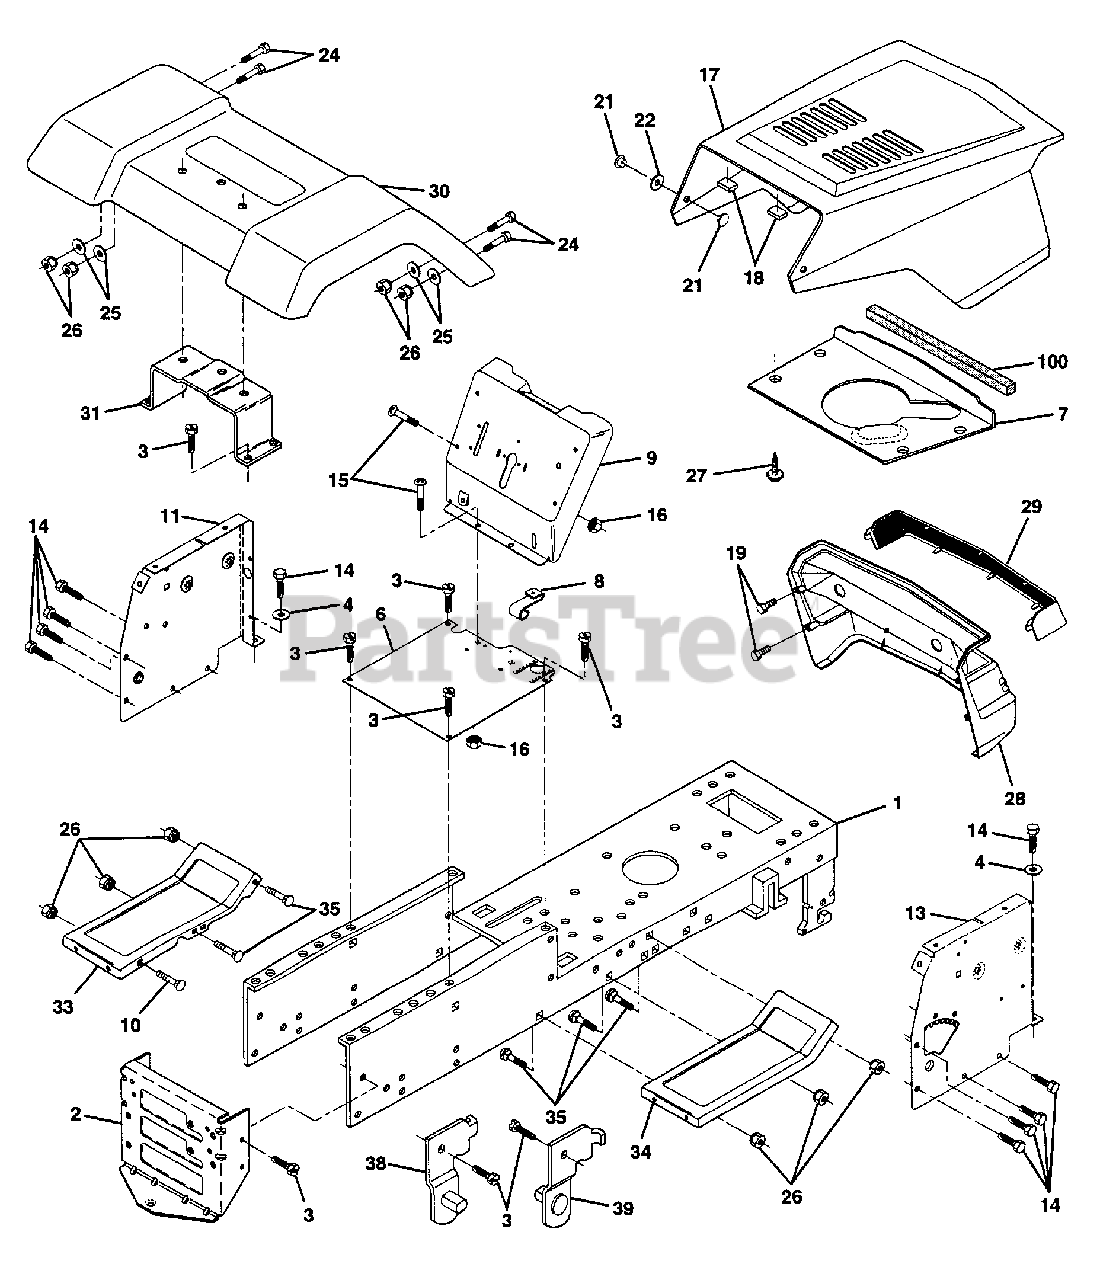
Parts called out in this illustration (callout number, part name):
1	CHASSIS.WLD.11GA
3	SCREW
4	WASHER
5	LOCKWASHER
7	"SHIELD,HEAT HOOD"
8	"CLIP,INSULATOR"
11	DASH PANEL LH
12	LOCKWASHER GT
14	SCREW LT
15	SCREW
19	SCREW SLTD HXHD
21	"RIVET,PLASTIC"
24	BOLT
25	WASHER
26	NUT
31	BRKT FENDER
33	FOOTREST.LH.LT/GT
34	FOOTREST.RH.LT/GT
35	BOLT
38	BRACKET ASM LH
39	BRACKET ASM RH
100	FOAM-STRIP LT
